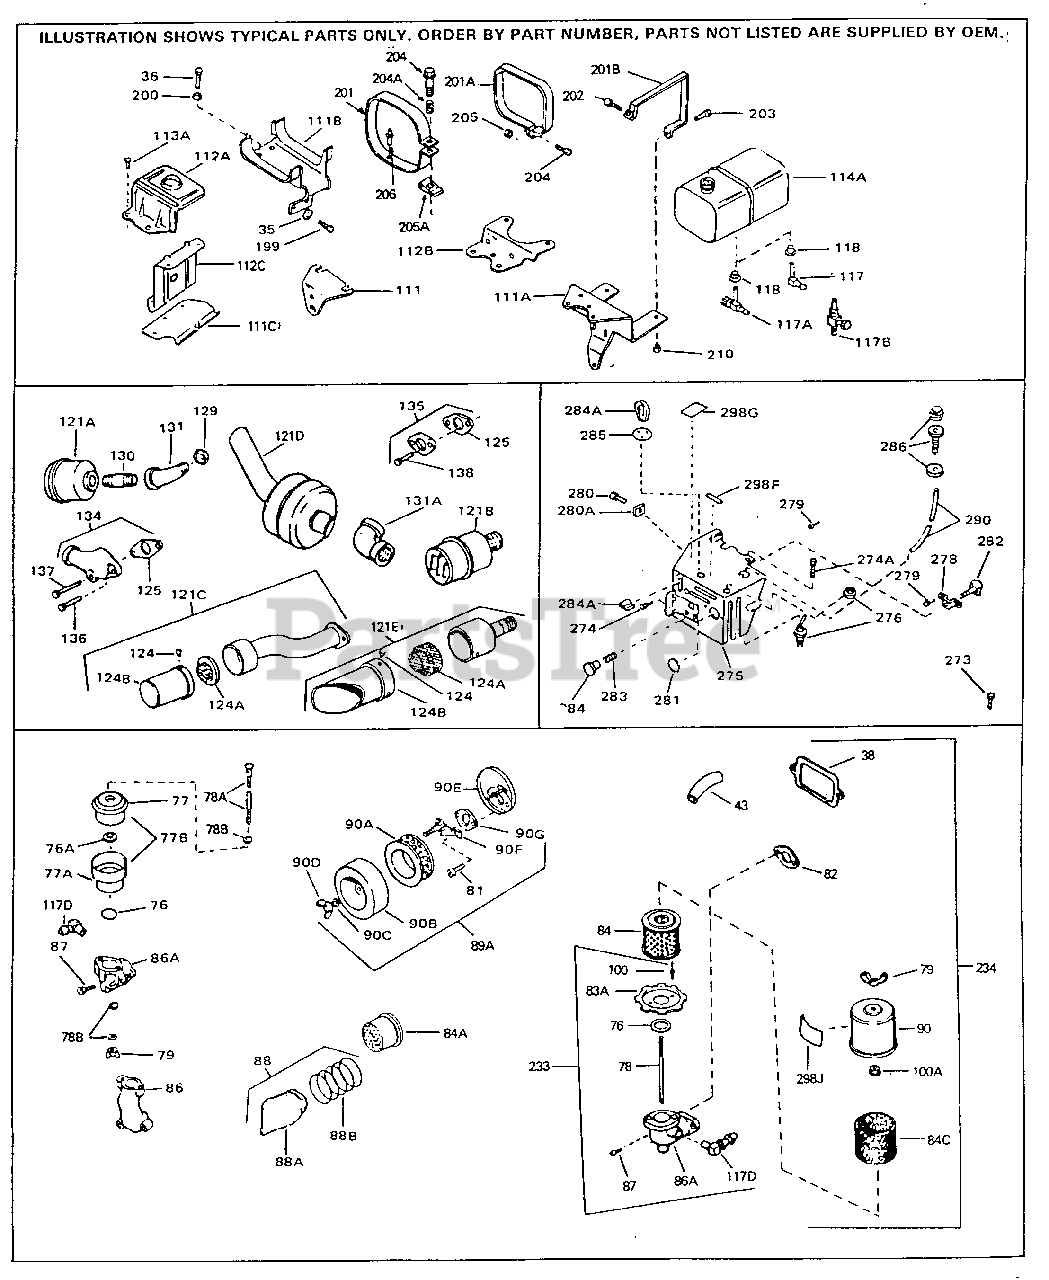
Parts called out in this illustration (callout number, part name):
35	Washer, Flat (Use as required)
36	Screw, 5/16-18 x 2" (Use as required)
36	Screw, 5/16-18 x 2-1/4" Use as requir ed
36	Screw, 5/16-18 x 2-1/2" Use as requir ed
38	* Gasket, Breather cover
81	Screw, 10-32 x 1/2"
81	Screw, 5/16-18 x 3/4"
81	Screw, 10-32 x 1-1/8" Use as require d
82	* Gasket, Air cleaner
84A	Air Filter
86A	Air Cleaner Elbow Assy. Use in 730561 only.
89A	Air Filter (Incl. 82,90A,90B,90D thru 90G,97 & 298B) (Use as req.)
111B	Bracket, Lower fuel tank
114A	Fuel Tank (Incl. 115)
117A	Valve, Fuel strainer & shut-off
117B	Valve, Fuel strainer & shut-off
117D	Fitting, Fuel line
121A	Muffler
121E	Muffler (Incl. 124, 124A & 124B) (Thi s spark arrester mufflercan be used o n any model)
124	Screw, 8-18 x 3/8"
124A	Muffler Screen (Use as required)
124B	Cover & Tube, Muffler Use as require d
125	* Gasket, Exhaust
129	Nut, Conduit (1/4" thick)
130	Nipple, Pipe (2.5")
131	Elbow, Exhaust (45 degree)
134	Muf.Adapter Kit (Incl. 125,136,137) A s req.
135	Muf.Adapter Kit (Incl. 125 & 138) As required
136	Screw, 5/16-18 x 1-1/2" Use as requir ed
137	Screw, 5/16-18 x 2-1/2" Use as requir ed
138	Screw, 5/16-18 x 3/4"
199	Screw, 1/4-28 x 7/16"
200	Washer, Flat
201A	Strap, Fuel tank
204	Screw, 1/4-20 x 1"
205	Nut, 1/4-20
233	Air Cleaner Elbow (Incl. 44,76,78,83A ,86A,100)(Use in 730561 ass'y. only)
234	Air Cleaner Kit (Incl. 38,43,44,76,78 ,79,82,83A,84,84C,86A,87,90,100A,233, 298J) (Use only on engines with an ex ternally ventedfully adjustable carbu retor.)
273	Screw, 10-32 x 5/16" Use as required
284A	Knob, Speed control
